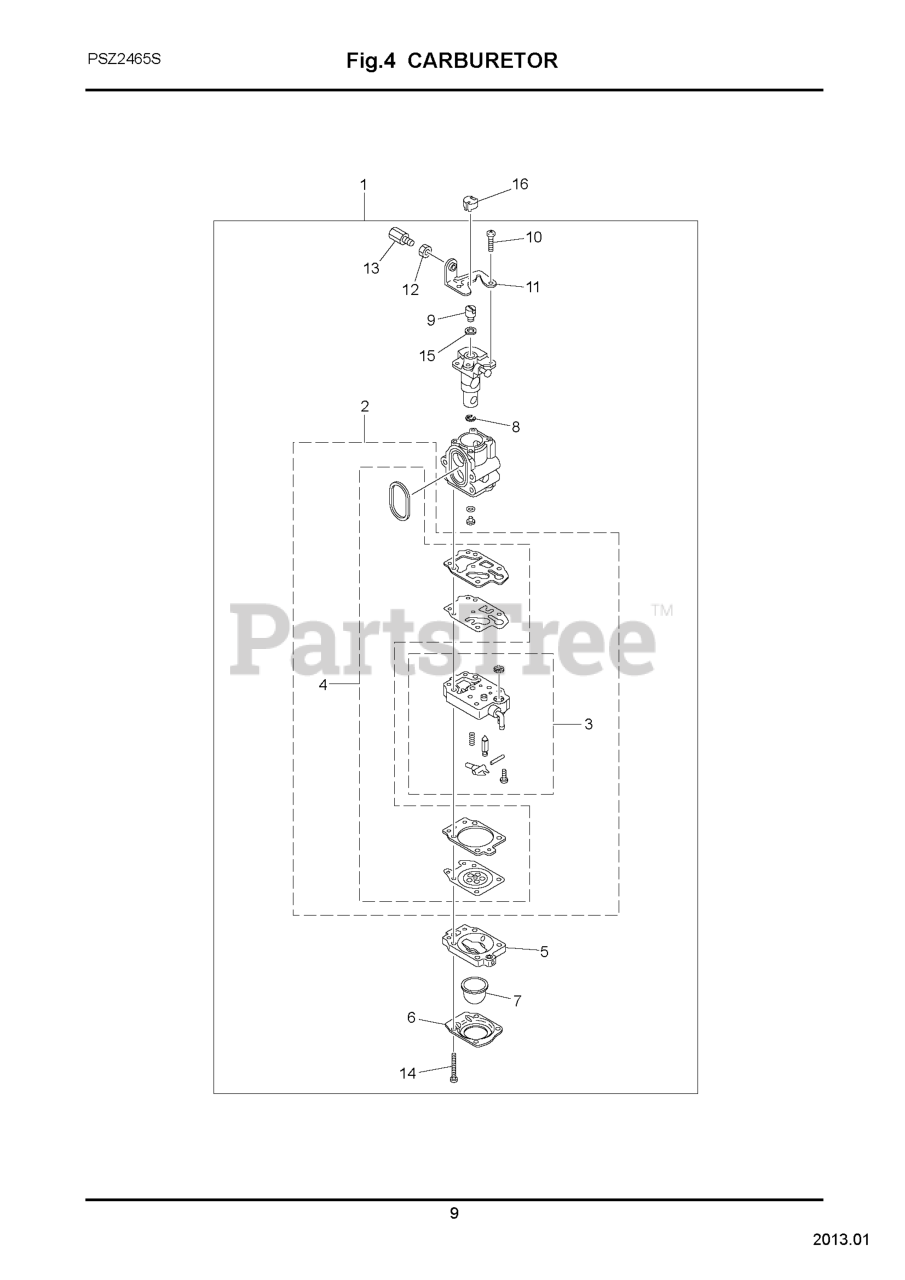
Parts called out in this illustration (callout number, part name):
1	CARBURETOR ASSY
2	REBUILD KIT
3	CARBURETOR BODY
4	GASKET KIT
6	1OVER
8	RING
9	SWIVEL
10	SCREW
11	BRACKET
12	NUT
13	ADJUSTER
15	WASHER
